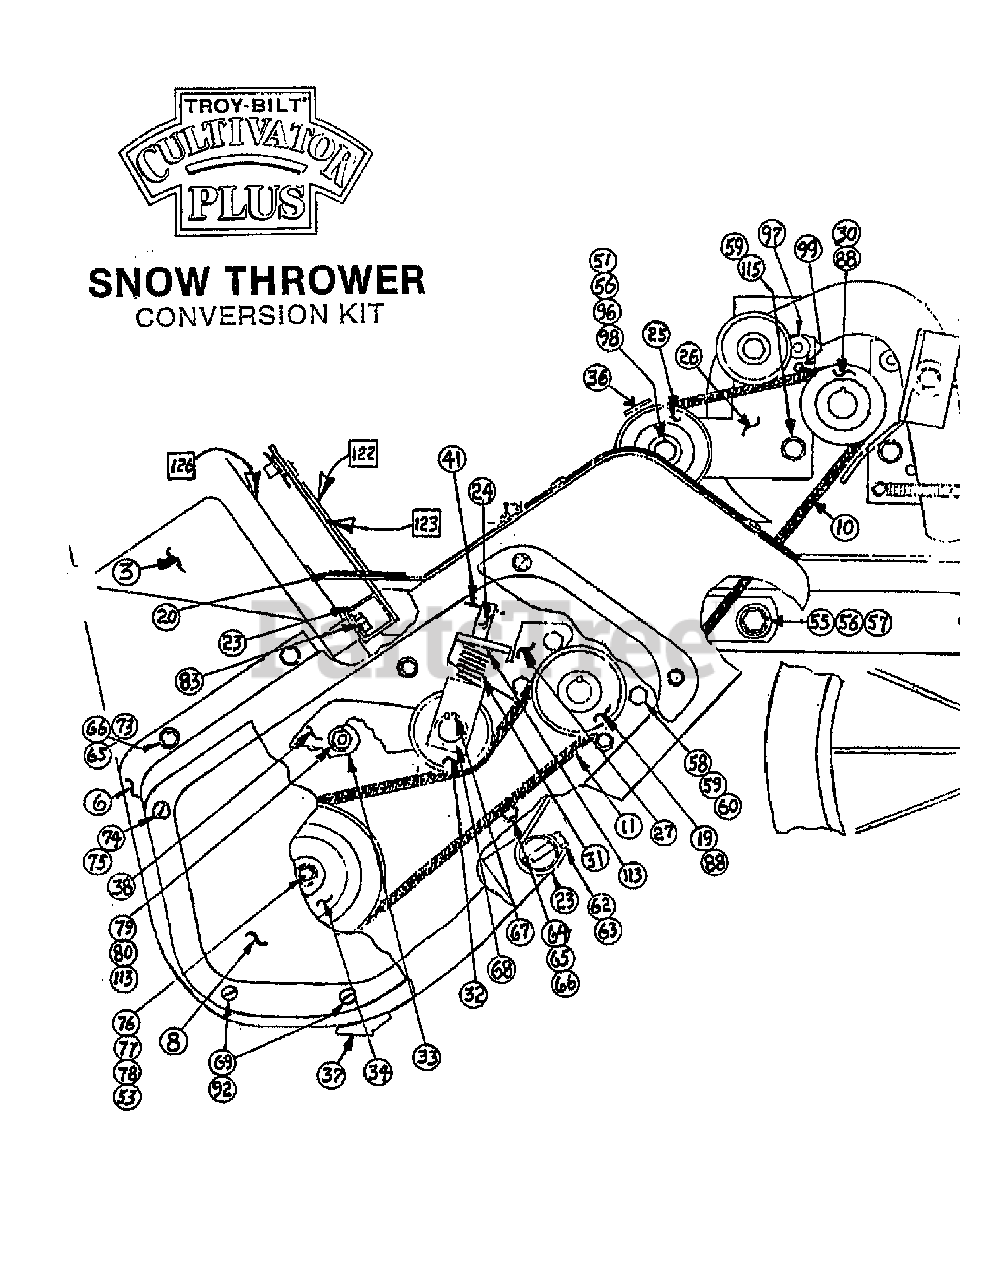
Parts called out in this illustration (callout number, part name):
3	WRAP SHEET W/DECALS
4	DEFLECTOR-VANE
5	MAIN GUARD W/DECAL
6	ASSM-SIDE PLATE LH
7	ASSM-PLATE RH
9	GUARD-DRIVE W/DECAL
10	BELT-V UPR DR SNOWBLOW
11	BELT-AUGER
12	BRKT-LOCKING PNT
13	DEFLECTOR-ROD WELD
15	SHAFT PICK-UP
16	BRKT-MOUNTING
18	PULLEY-ENGINE PICK-UP
19	PULLEY-AUGER DRIVE
20	SHIELD-WEATHER
21	ASSM-PIVOT VANE
22	ROD-LINKAGE
23	BRKT-MOUNTING WELD
24	HOLDER-IDLER WELD
25	PULLEY-IDLER
26	ASSM-IDLER PLATE
27	PLATE-MOUNTING
28	HANDLE-VANE CONTROL
29	GRIP-VANE CONTROL
30	PULLEY-ENGINE 4L
31	SPRING-COMPRESSION
32	ASSM-IDLER PULLEY
33	BUSHING-PIVOT
34	PULLEY-AUGER
35	STOP-OVERCENTER
36	GUIDE-BELT
38	ASSM-IDLER ARM
39	SPRING-AUGER STOP
42	ASSM-RECOIL GUARD
43	PLATE-AUGER
46	SUPPORT-AUGER
47	ASSM-BEARING
49	ASSM-SWITCH
50	COVER-CARB W/DECAL
51	D SPACER-IDLER
52	BOLT
53	WASHER
54	NUT
55	BOLT
56	WASHER
57	WASHER
58	BOLT
59	WASHER
60	NUT
61	WASHER
63	SCR-HH 5/16-18 X .20 STH ZP
64	BOLT
65	WASHER
66	NUT
67	RING-SNAP
68	WASHER-FLAT 3/4
69	SCR-RD HD #10-24 X 3/4
70	WASHER
71	NUT
72	SCR-HH 1/4-20 X 6
75	SCR-HEX TYPE A #10-.500
76	BOLT-HH 1/4-28 X 3/4
77	WASHER-1.06 X .25 X .067
78	KEY-WOODRUFF 1/8 X 1/2
79	BOLT
80	NUT
81	NUT
83	SCR-SHAKE PR 1/4-15 X 3/4
84	SCR-RH M10-24 X .50 ZP
86	CUSHION-6.74 5 LONG
87	CUSHION-3.75 LONG
88	KEY
89	PIN-HITCH ZP
90	KEY-.188 SQ X 1.25
91	SCR-HEX SOC FL #10-24
92	NUT
93	BRACE-SUPPORT
94	SCR-RD HD #8-32 X 5/8
95	NUT-LOCK #8-32
96	NUT
97	SCR-FLT HD 5/16-24
98	BOLT
99	PIN
102	LEVER-REMOTE CHOKE
103	WASHER
104	N KNOB-CHOKE LEVER
105	ENGINE STUD
106	SCR-HH 5/16-18X.63 G5
107	WASHER
110	CLAMP-CABLE
112	HINGE-SHROUD
113	WASHER
114	WASHER-FLAT 7/16 SAE
115	SCR-FLHH 5/16-24 X .75 ZP
117	DECAL-CARB COVER
118	DECAL-"CULTIVATOR-PLUS"
119	DECAL-WARN. BELT CVR
122	DECAL-DEFLECTOR PLT LT
123	DECAL-DEFLECTOR PLT RT
124	DECAL-ATTACH INST
126	DECAL-ANSI
